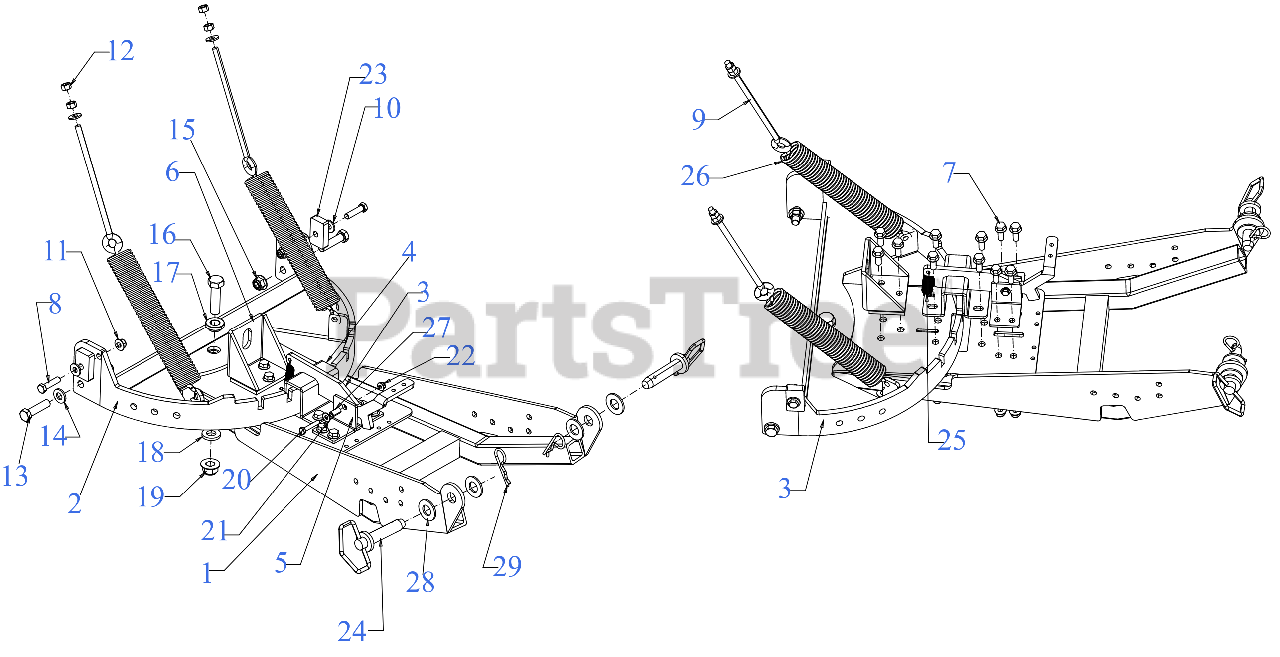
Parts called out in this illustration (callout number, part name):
1	LIFT ARM
2	SWIVEL PLATE
3	PIVOT LOCK LEVER
4	PIVOT LEVER SUPPORT BRACKET
5	PIVOT LEVER RISER
6	WINCH ATTACHMENT BRACKET
7	HEX SCREW 3/8-16
8	SCREW 3/8-16 x 1.50
9	3/8"-16 X 8" EYE BOLT
10	FLAT WASHER .385X.870X.090
12	HEX NUT
13	SCREW 1/2-13 x 2 GR5
14	FLAT WASHER
16	SCREW 5/8-11 x 2.25 GR5
17	5/8" PIVOT RING
18	FLAT WASHER .635X1.24X.181
19	FLANGE LOCK NUT
20	SCREW 1/4-20 x 1.50 GR.5
21	FLAT WASHER
22	FLANGE LOCK NUT
23	STOP BLOCK
24	QUICK RELEASE PIN
25	LOCK LEVER SPRING
26	10" EXTENSION SPRING
27	1/4" ALUMINUM SPACER
28	FLAT WASHER
29	5/8" COTTER PIN
